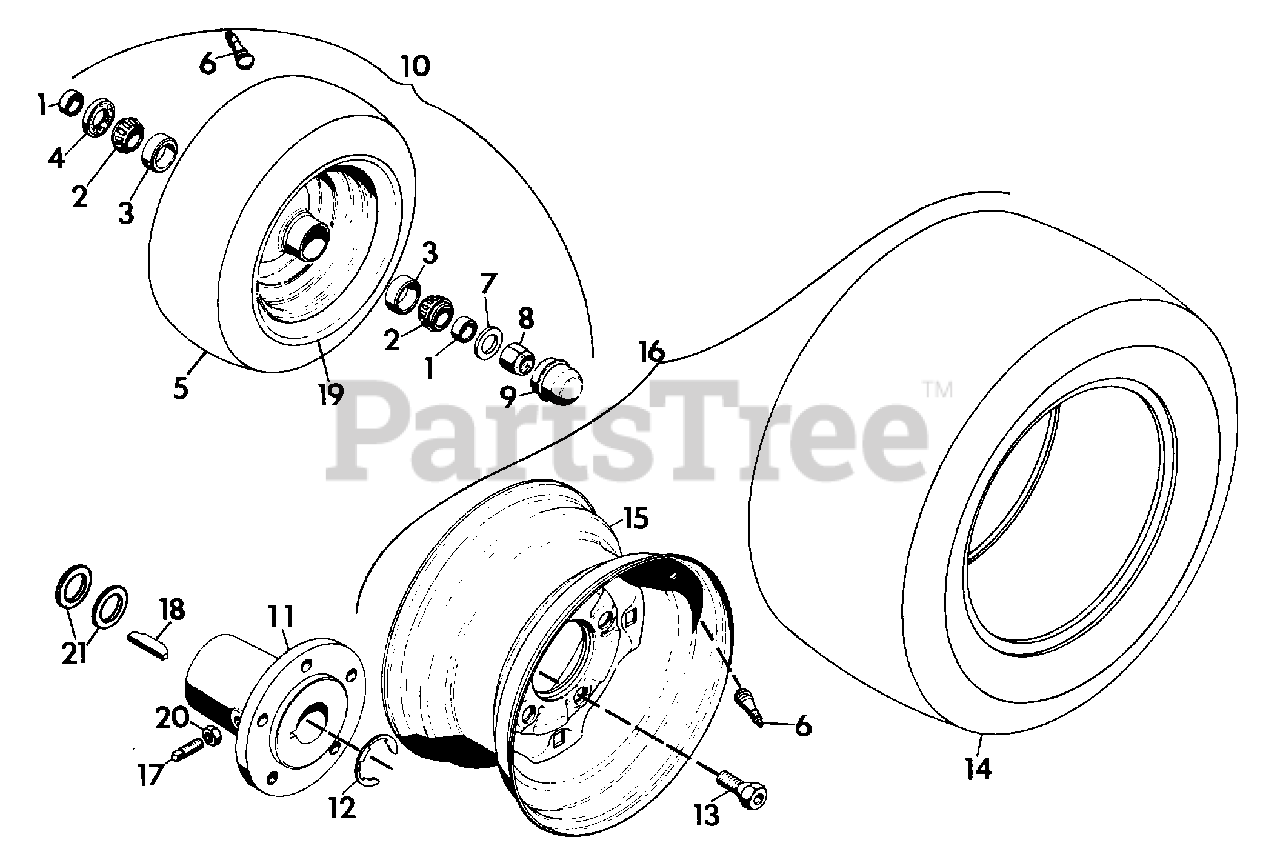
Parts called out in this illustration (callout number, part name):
1	SPACER
2	BEARING, CONE LM 11949
3	BEARING, CUP LM 11910
4	SEAL, OIL
5	TIRE, FRONT 16X6.50-8
5	TIRE, FRONT 16X7.50-8
6	ASSEMBLY, VALVE STEM
7	WASHER, FLAT .656X1.312X.095
8	NUT, LOCK 5/8-11
9	CAP
10	ASSEMBLY, FRONT WHEEL 16X6.50-8
10	ASSEMBLY, FRONT WHEEL 16X7.50-8
11	HUB, WHEEL
12	E-RING, 1.125 SHAFT
13	BOLT, HUB 7/16-20X.75(SPECIAL)
14	TIRE, REAR 23X8.50-12
14	TIRE, REAR 23X10.50-12
15	RIM, WELDMENT
16	ASSEMBLY, REAR WHEEL 23X8.50-12
16	ASSEMBLY, REAR WHEEL 23X10.50-12
17	SCREW, SET 3/8-16X1.25 SHCP
18	KEY, WOODRUFF .250X2.125 SOFT
19	RIM, FRONT WHEEL ASSEMBLY
20	NUT, JAM 3/8-16
21	WASHER, FLAT .813X1.37X.100
